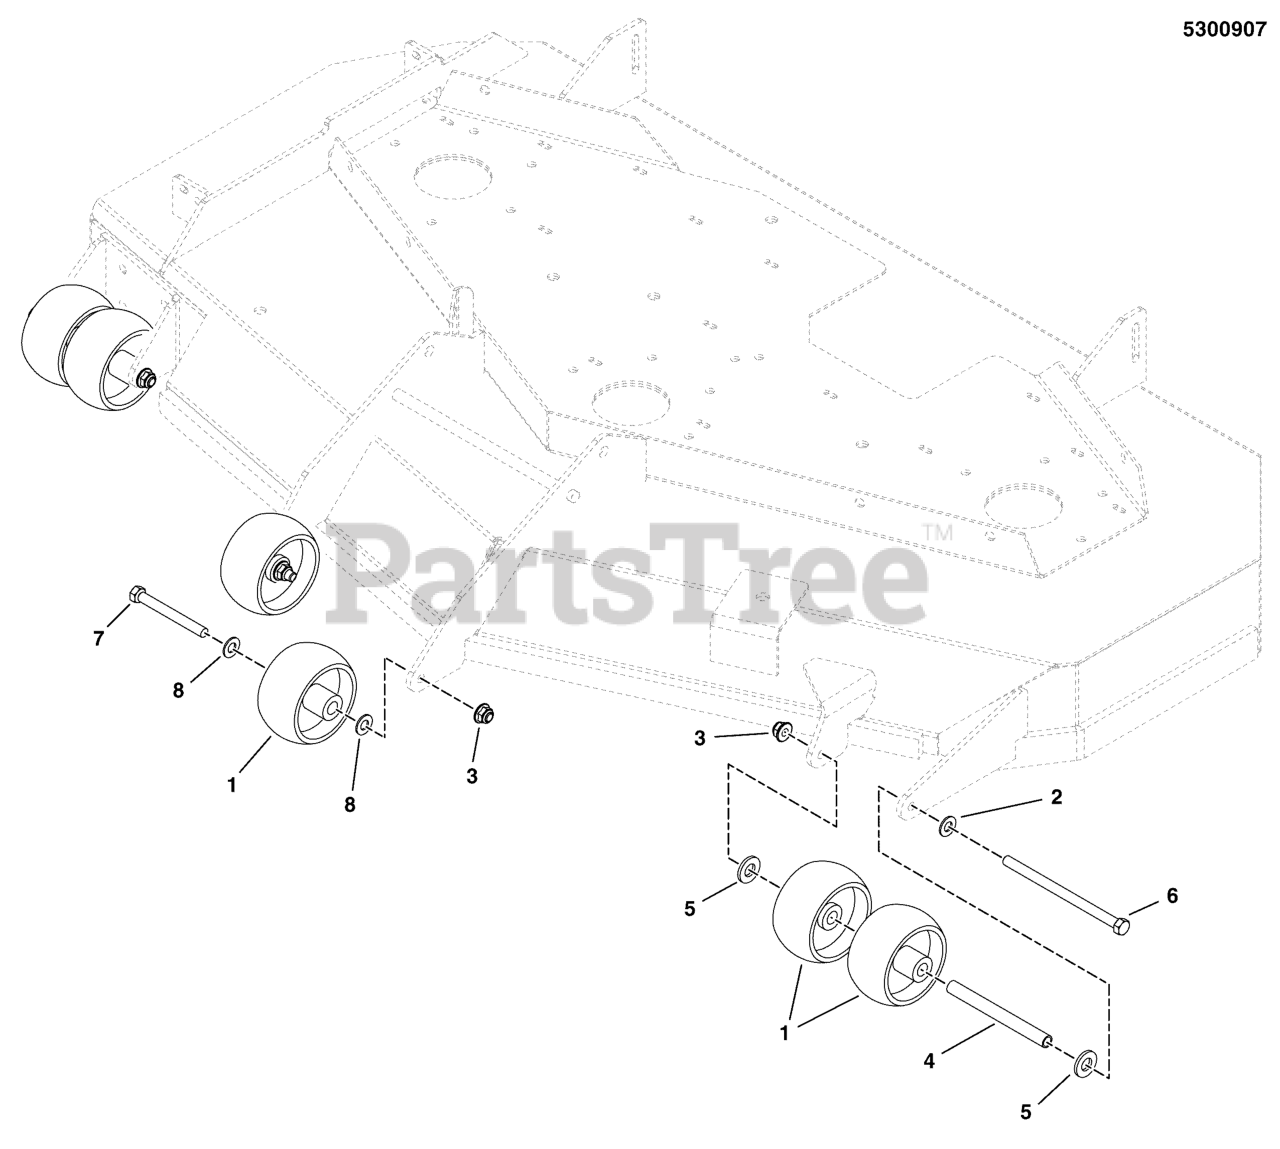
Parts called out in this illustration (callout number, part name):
1	WHEEL- 2.00 WIDE 3.88 DIA 0.531ID POLY
2	WASHER, 3/8 SAE
3	NUT, 3/8-16 HEX NYLOCK FLANGE
4	SPACER, .38 X .50 X 5.06
5	WASHER, 1/2 SAE
6	BOLT, 3/8-16 X 6" GD5 CZ
7	BOLT-WHEEL 3/8-16X2.781 .750 THRD YELLOW
8	WASHER,.516IDX.875ODX.06,FLAT,ZC/CL
